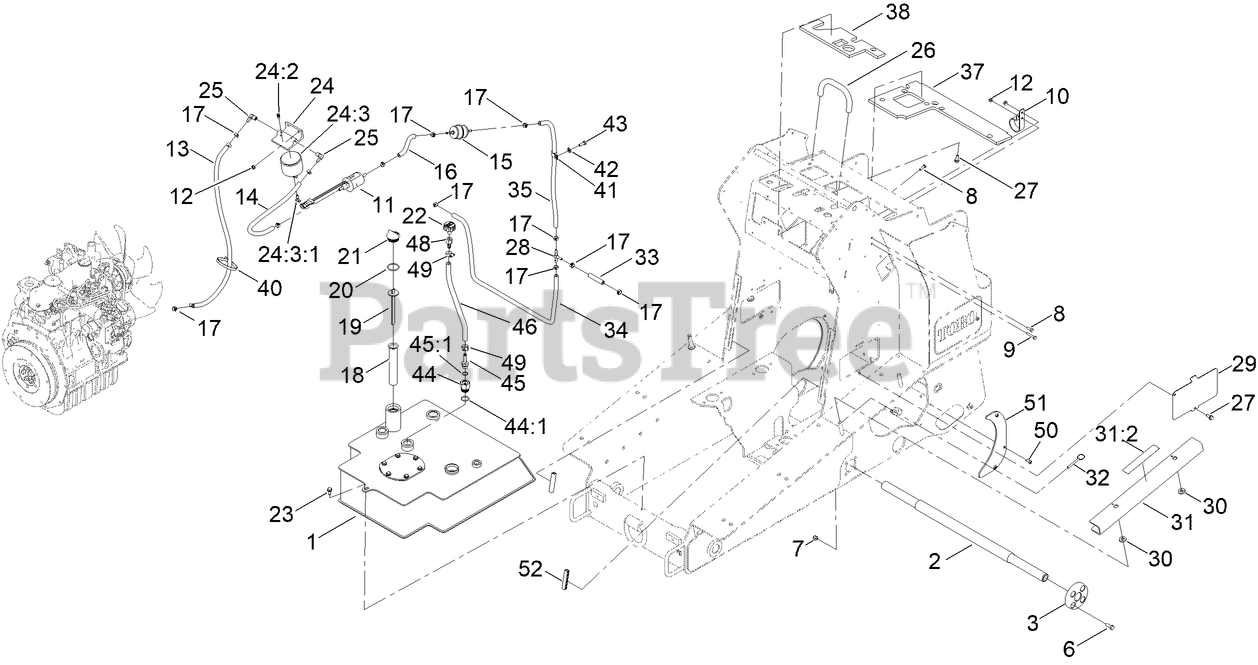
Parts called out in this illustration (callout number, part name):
1	TANK-HYD
2	SHAFT-TRACK
3	HUB-SHAFT
6	SCREW-HH
7	NUT-LOCK, NI
8	SCREW-HH
9	SCREW-HH
10	BRACKET-PUMP, FUEL
11	PUMP-FUEL
12	NUT-HF
13	HOSE-FUEL
14	HOSE-FUEL
15	FILTER-INLINE
16	HOSE-FUEL
17	CLAMP-HOSE
18	FILTER-SCREEN
19	DIPSTICK
20	O-RING
21	PLUG-PLASTIC
22	BREATHER
23	SCREW-THD ROLL, HWH
24	FILTER HEAD ASM
24:2	VENT-AIR
24:3	ELEMENT-SPIN ON
24:3:1	VALVE-DRAIN
25	FITTING-HYD, 90
26	BAR-REFERENCE
27	SCREW-HHF
28	FITTING-TEE, BARBED
29	PLATE-COVER, ACCESS
30	WASHER-NEOPRENE
31	ARM-LOCKING
31:2	DECAL-DANGER
32	PIN-COTTERLESS
33	HOSE-FUEL
34	HOSE-FUEL
35	HOSE-FUEL
37	FOAM-HEAT SHIELD
38	FOAM-HEAT SHIELD
40	TIE-CABLE
41	CLAMP-R
42	WASHER-FLAT
43	SCREW-HH
44	FITTING-STRAIGHT
44:1	O-RING
45	FITTING-STR
45:1	O-RING
48	FITTING-FEMALE, BARBED
49	CLAMP-HOSE
50	PLATE-DIRT
51	SCREW-BHTF
